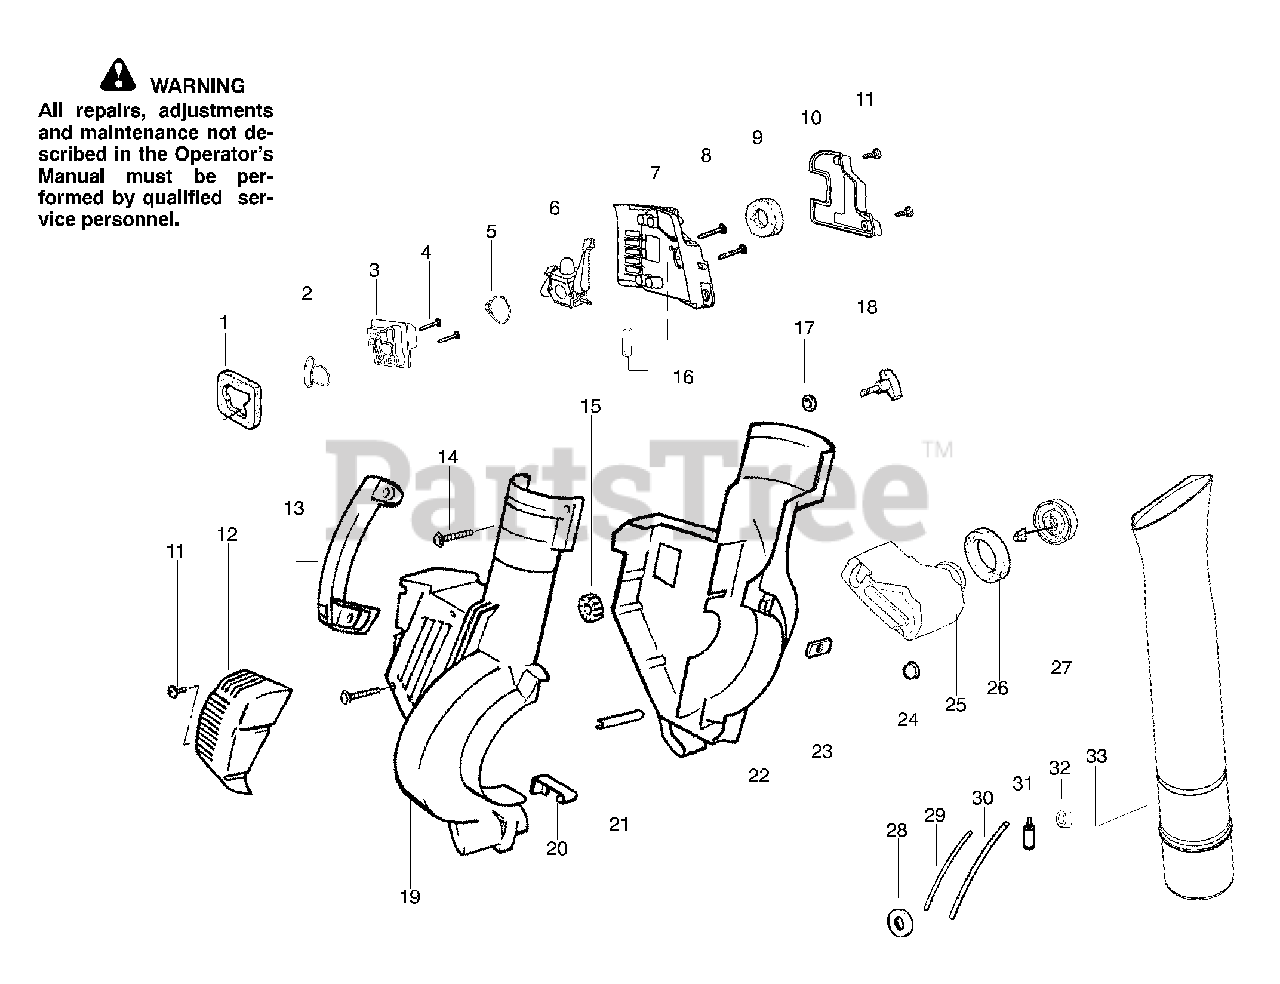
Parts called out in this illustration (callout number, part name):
1	Air Dam (kit)
2	Gasket-Adapter (kit)
3	Carburetor Adaptor
5	Gasket-Carburetor (kit)
6	Kit-Carb Ass'y. (C1Q-W11)
6	Kit-Carb Ass'y. (C1Q-W11C)
8	Screw-Carb.
9	Filter-Air
10	Cover-Air Filter
12	Guard-Muffler
15	Isolator
16	Foam 25.4mm (kit)
18	Knob-Blower
19	Housing-Right
20	Spring-Cover Latch
21	Guide-Starter Rope
22	Housing-Left
24	Isolator-Crankcase
25	Assy-Fuel Tank
26	Gasket-Fuel Tank
27	Fuel Cap w/Retainer
28	Grommet-Shroud
29	Kit-Line Carb/Purge
30	Kit-Line Tank/Purge
31	Assy-Fuel Pick-up
32	Grommet-Fuel line (kit)
33	Tube-Blower
